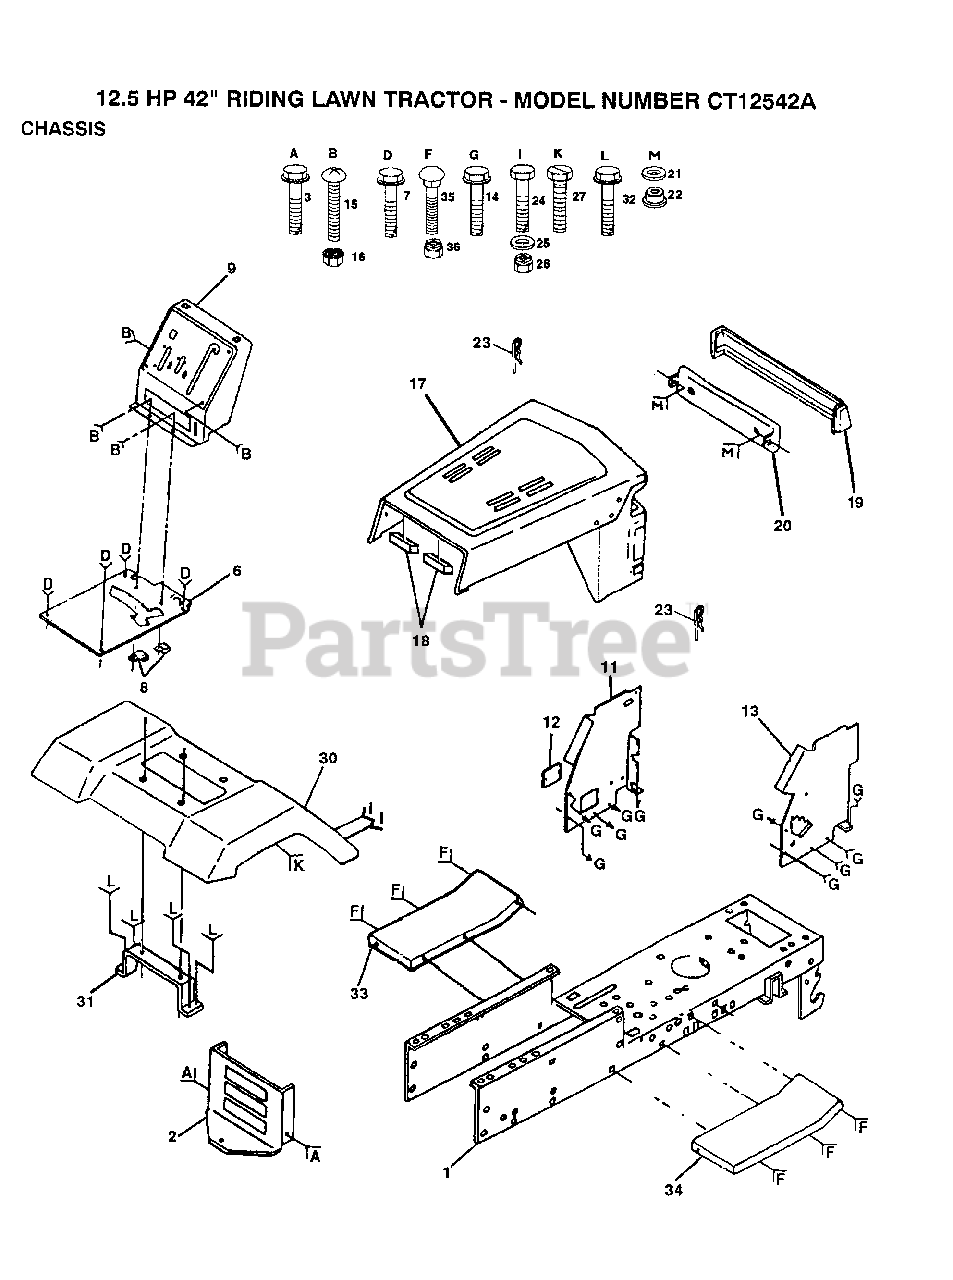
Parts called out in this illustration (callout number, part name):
1	CHASSIS WELDMENT
3	SCREW
7	SCREW LT
8	CLIP T
11	PANEL DASH LH
12	COVER ACCESS
14	SCREW LT
15	SCREW
17	HOOD/GRILL ASM
19	LENS SERVICE KIT
21	WASHER PM
22	PAL NUT LT
23	SPRING.RETAINER
25	WASHER
27	SCREW LT
32	SCREW
33	FOOTREST LH
34	FOOTREST
35	BOLT
